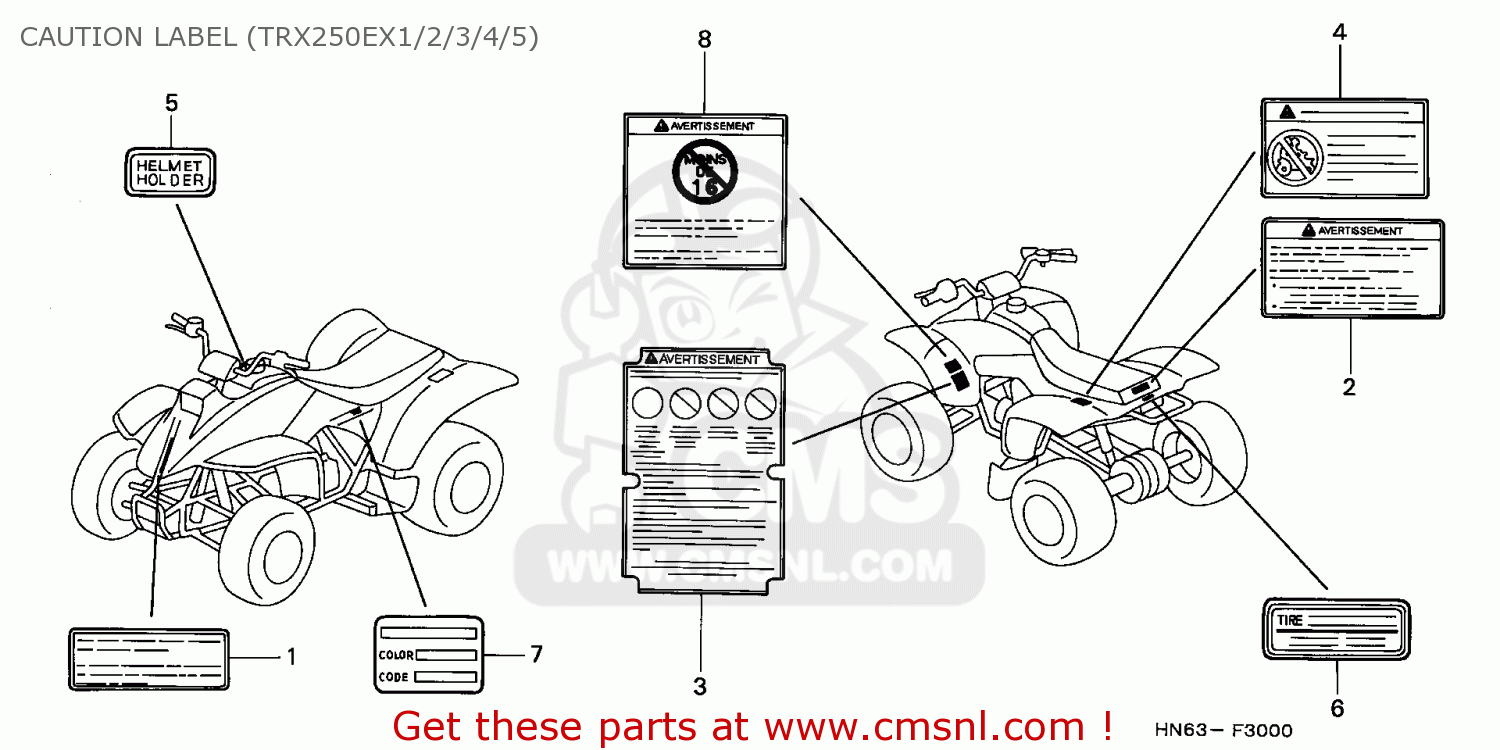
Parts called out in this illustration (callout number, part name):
1	LABEL,IGNITION NO
2	LABEL,PASSENGER WARN
3	LABEL GENERAL WAR
4	LABEL,TIRE&OVERLO
7	LABEL,COLO*TYPE1*
8	LABEL,SIXTEEN AGE (F
